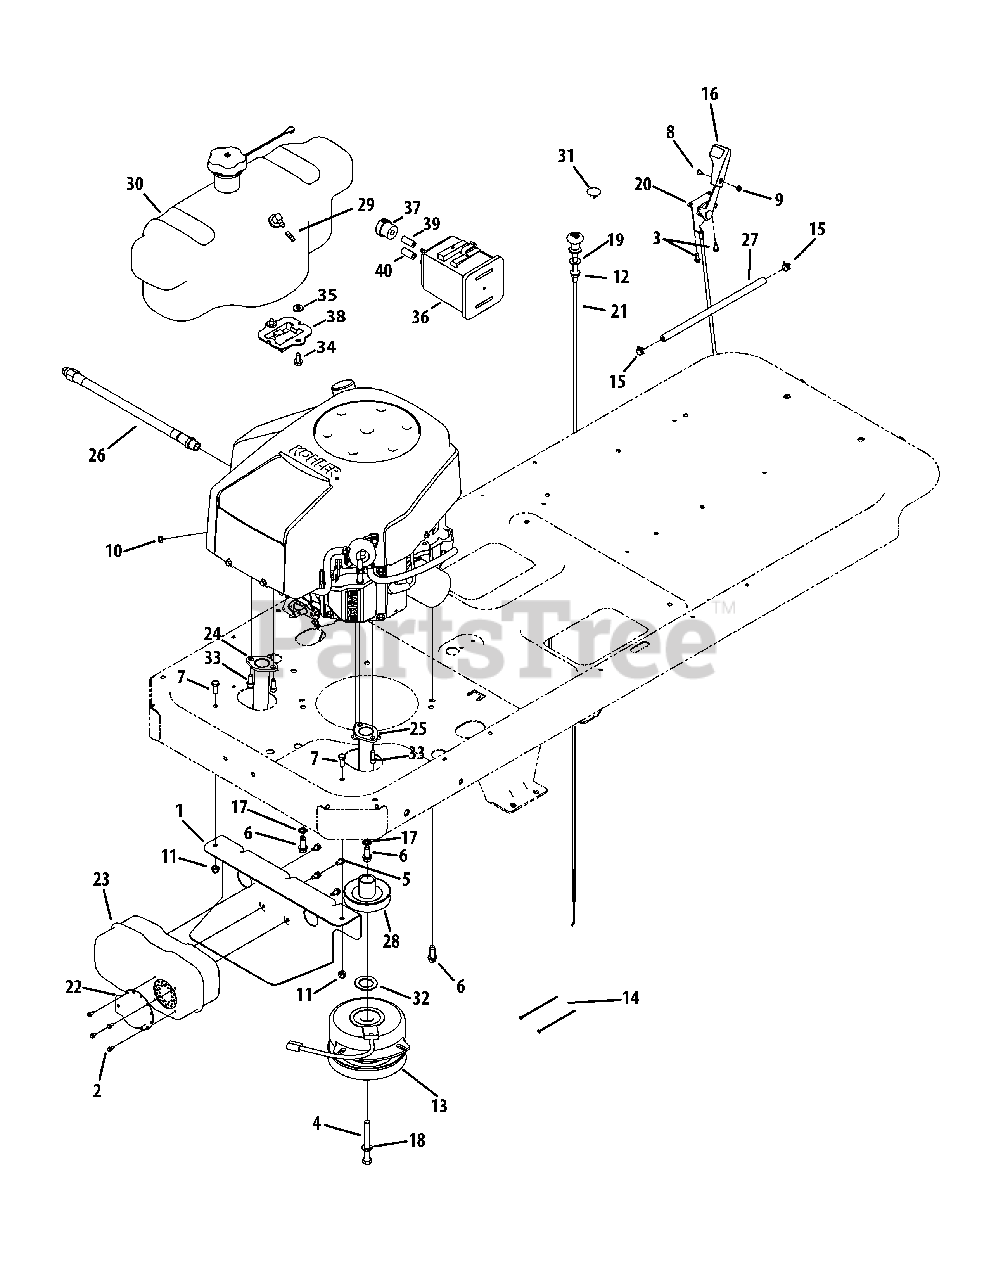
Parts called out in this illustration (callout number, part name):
1	Muffler Mount Bracket
2	Hex Washer Screw, #8-18 x .500
3	Screw, 1/4-14 x .625
4	Hex Screw, 7/16-20 x 3.25
5	Hex Washer Screw, 1/4-20 x .500
6	Hex Washer Screw, 3/8-16 x 1.000
7	Hex Washer Screw, 5/16-18 x .75
8	Machine Screw, #8-32 x .375
9	Hex Nut, #8-32
10	Sems Nut, 1/4-20
11	Flange Lock Nut, 5/16-18
12	Flange Lock Nut, 3/8-16
13	Electric PTO Clutch
14	Cable Tie
15	Hose Clamp
16	Throttle Control Knob
17	Lock Washer, 3/8
18	Lock Washer, 7/16
19	Flat Washer, .406 x .875 x .059
20	Throttle/Choke Control Cable
21	Choke Cable
22	Muffler Deflector
23	Dual Inlet Muffler
24	Exhaust Pipe, LH
25	Exhaust Pipe, RH
26	Oil Drain Hose
27	Fuel Hose
28	Engine Pulley
29	Hose Vent, 3/16 EPA
30	Fuel Tank Assembly
30	Fuel Tank Bushing
30	Rubber Grommet
30	Fuel Pick-Up Fitting
30	Fuel Cap
30	Rollover Valve
31	Choke Plug
32	Flat Washer, 1.03 x 1.620 x .095
33	Screw, 5/16-18 x .750
34	Screw 5/16-18 x .875
35	Washer, Flat, .344 x .750 x .120
36	Canister, Carbon, 5 Gallon
37	Filter, Vent, Canister
38	Bracket., Adapter, Canister
39	Hose, Fuel, Low Perm., White
40	Hose, Fuel, Low Perm., Yellow
